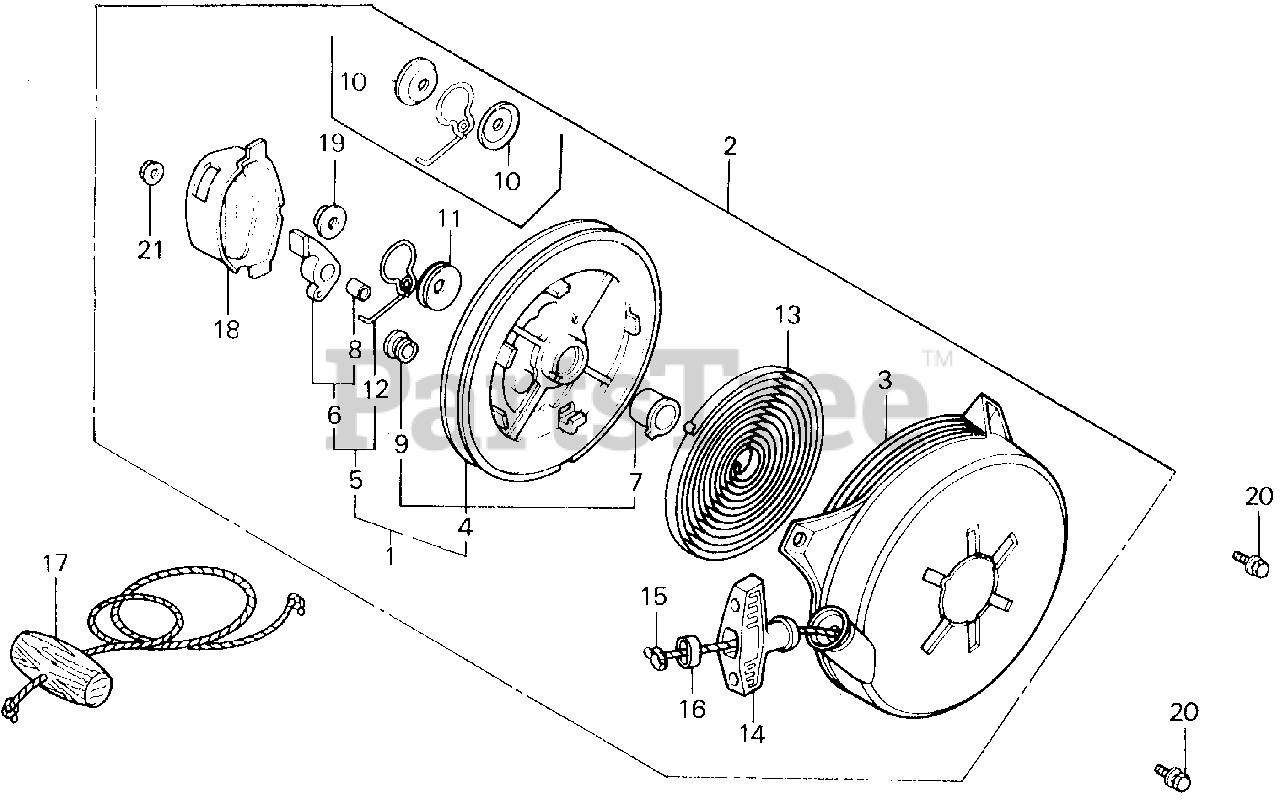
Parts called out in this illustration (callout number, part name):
1	REEL KIT, STARTER
2	STARTER ASSY., RECOIL *R8* (BRIGHT RED)
3	CASE, STARTER *R8* (BRIGHT RED)
4	REEL KIT, STARTER
4	REEL, STARTER
5	RATCHET KIT
6	RATCHET KIT
6	RATCHET
7	BOSS, REEL
8	BUSH, RATCHET (NOT AVAILABLE)
8	BUSH, RATCHET
9	BUSH, REEL STARTER
10	PLATE, FRICTION
11	PLATE, FRICTION
12	RATCHET KIT
12	SPRING, FRICTION
13	SPRING, RETURN
14	GRIP, STARTER
15	ROPE, STARTER
16	SUPPORT, GRIP
17	ROPE, STARTER Use from Engine SN 1779881.
18	COVER, STARTER REEL
19	NUT, SELF-LOCK (8MM)
20	BOLT-WASHER (6X10)
21	NUT, FLANGE (5MM)
